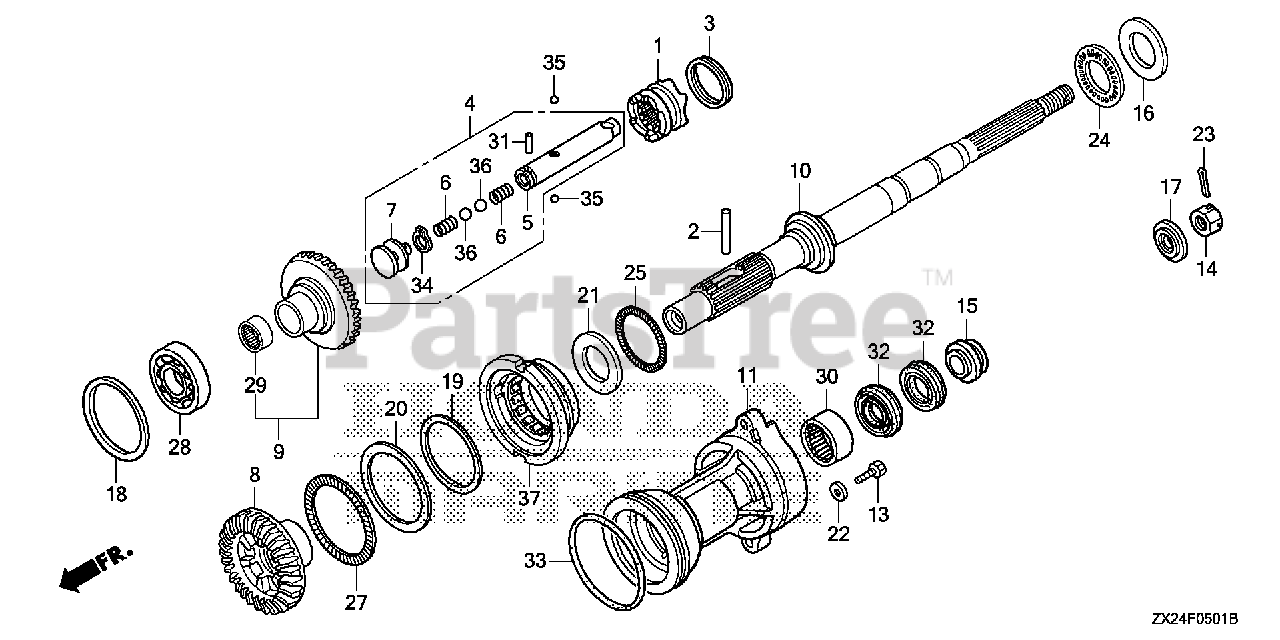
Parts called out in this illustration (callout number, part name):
1	SHIFTER, CLUTCH
2	PIN, SHIFTER (8X50)
3	RING, CROSS PIN
4	SLIDER, SHIFT
5	SLIDER, SHIFT
6	SPRING, SHIFT
7	PLATE, SHIFT
8	GEAR, BEVEL (24T) (FORWARD)(COUNTER ROTATION)
9	GEAR, BEVEL (24T) (REVERSE)(COUNTER ROTATION)
10	SHAFT, PROPELLER
11	HOLDER, PROPELLER SHAFT *NHB14M* (AQUA MARINE SILVER METALLIC)
11	HOLDER, PROPELLER SHAFT *NH565* (GRAND PRIX WHITE)
13	BOLT, HEX. (12X45)
14	NUT, CASTLE (18MM)
15	WASHER, PROPELLER THRUST
16	WASHER, THRUST BEARING
17	WASHER, PROPELLER
18	SHIM A, BEVEL (0.10)
18	SHIM B, BEVEL (0.15)
18	SHIM C, BEVEL (0.30)
18	SHIM D, BEVEL (0.50)
19	SHIM A, BEVEL (0.10) (COUNTER ROTATION)
19	SHIM B, BEVEL (0.15) (COUNTER ROTATION)
19	SHIM C, BEVEL (0.30) (COUNTER ROTATION)
19	SHIM D, BEVEL (0.50) (COUNTER ROTATION)
20	WASHER, THRUST (85X110X2)
21	WASHER, THRUST (48X74X3) (COUNTER ROTATION)
22	WASHER, PLAIN (12MM)
23	PIN, SPLIT (4.0)
24	BEARING, THRUST (F)
25	BEARING, NEEDLE (50X72X4.5)
27	BEARING, THRUST NEEDLE (85X110X4)
28	BEARING, RADIAL BALL (55X100X21)
29	BEARING, NEEDLE (28X39X30)
30	BEARING, NEEDLE (32X42X30)
31	ROLLER (3X13.8)
32	SEAL, WATER (30X45X7)
33	O-RING (121X3.1)
34	CIRCLIP (OUTER) (15MM)
35	BALL, STEEL (#7) (7/32)
36	BALL, STEEL (#12) (3/8)
37	HOLDER ASSY., BEARING (COUNTER ROTATION)
